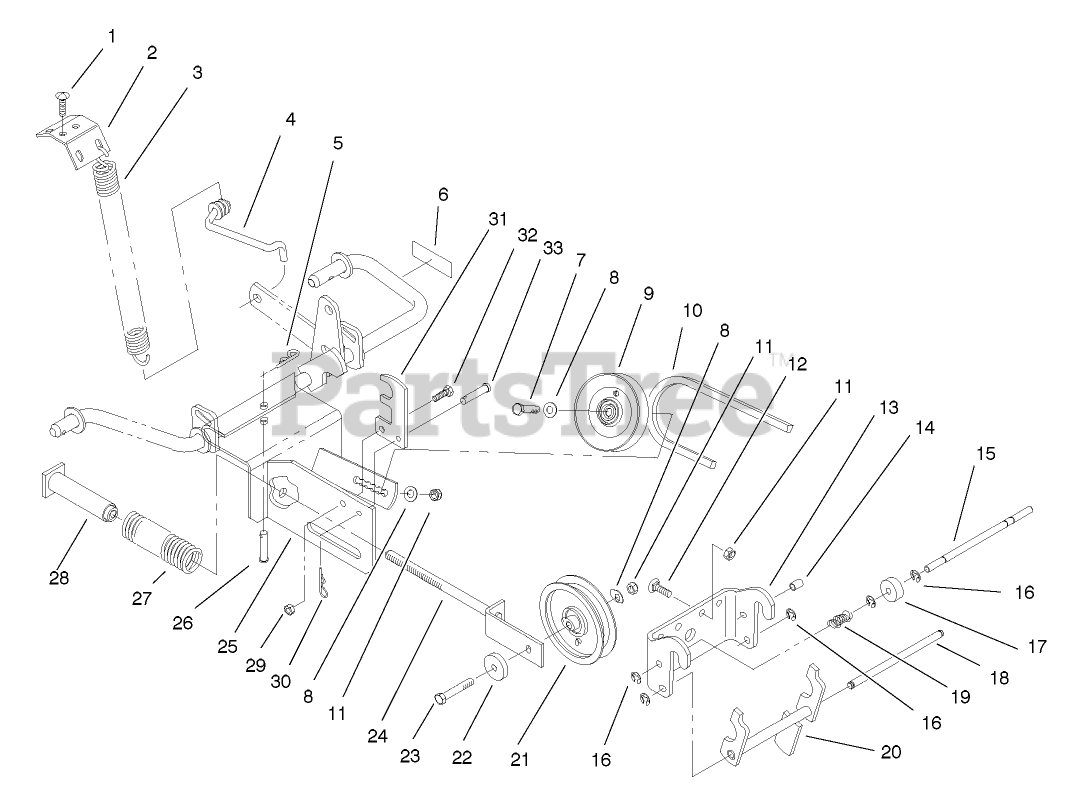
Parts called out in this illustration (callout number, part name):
1	SCREW-CARR
2	BRACKET
3	SPRING-EXTENSION
4	SPRING ROD
5	PIN-HAIR
6	DECAL-WARNING
7	SCREW-HH
8	WASHER-FLAT
9	PULLEY-IDLER
10	V-BELT
11	NUT-LOCK, NI
12	SCREW-CARR
13	HITCH-FRONT
14	CAP-ROD, PLUNGER
15	ROD-LOCK
16	RING-RETAINING
18	ROD-LATCH PIVOT
19	SPRING
20	LATCH
21	PULLEY - FLAT IDLER
22	BUSHING
23	SCREW-HH
24	IDLER SLIDE
25	IDLER SUPPORT
26	Clevis Pin
27	SPRING-COMPRESSION
28	SPRING-TENSIONER
29	NUT-LOCK, NI
30	PIN-HAIR
31	CATCH-IDLER SUPPORT
32	SCREW-HH
33	PIN-CLEVIS
